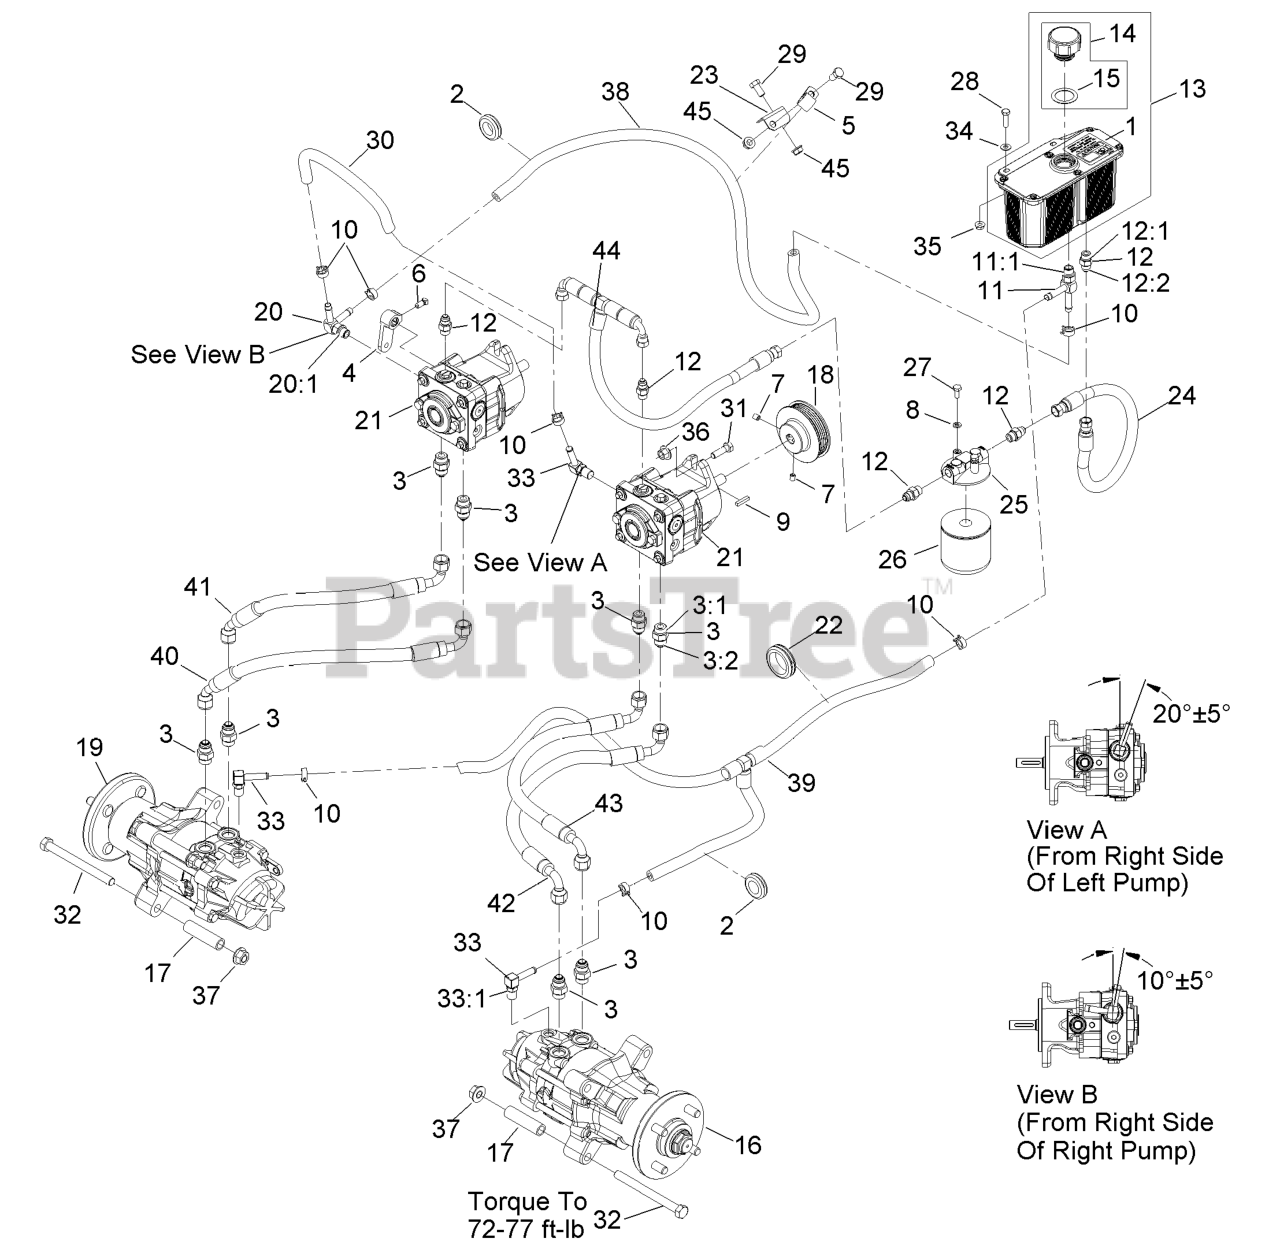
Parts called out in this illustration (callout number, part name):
1	DECAL-HYDRAULIC TANK
2	GROMMET
3	FITTING-STRAIGHT
4	ARM-CONTROL, PUMP
5	CLIP-LOOM
6	SCREW-SET
7	SCREW-SET
8	WASHER-LOCK
10	CLAMP-HOSE
11	ADAPTER-RUN, TEE
11:1	O-RING
12	FITTING-STRAIGHT
12:1	O-RING
13	HYD RESERVOIR ASM
14	KIT,HYD RES CAP W/GASKET
15	GASKET-CAP
16	MOTOR,PRM18-LH
19	MOTOR,PRM18-RH
20	ADAPTER-TEE
20:1	O-RING
22	GROMMET
23	BRACKET-CLAMP
24	HYDRAULIC HOSE ASM
25	HEAD-FILTER
26	FILTER-25 MICRON, BI-DIRE
26	ELEMENT-FILTER, WINTER
27	SCREW-HH
28	SCREW-HH
29	SCREW-HH
30	HOSE-HYD
31	SCREW-HH
32	SCREW-HH
33	FITTING-ELBOW, 90
34	WASHER-FLAT
36	NUT-FLANGE
37	NUT-HHF
38	HOSE-HYD
39	ASM,HYDRAULIC HOSE
40	ASM,HYDRAULIC HOSE
41	ASM,HYDRAULIC HOSE
42	ASM,HYDRAULIC HOSE
43	ASM,HYDRAULIC HOSE
44	HYDRAULIC HOSE ASM
45	NUT-HHF, WHIZ
